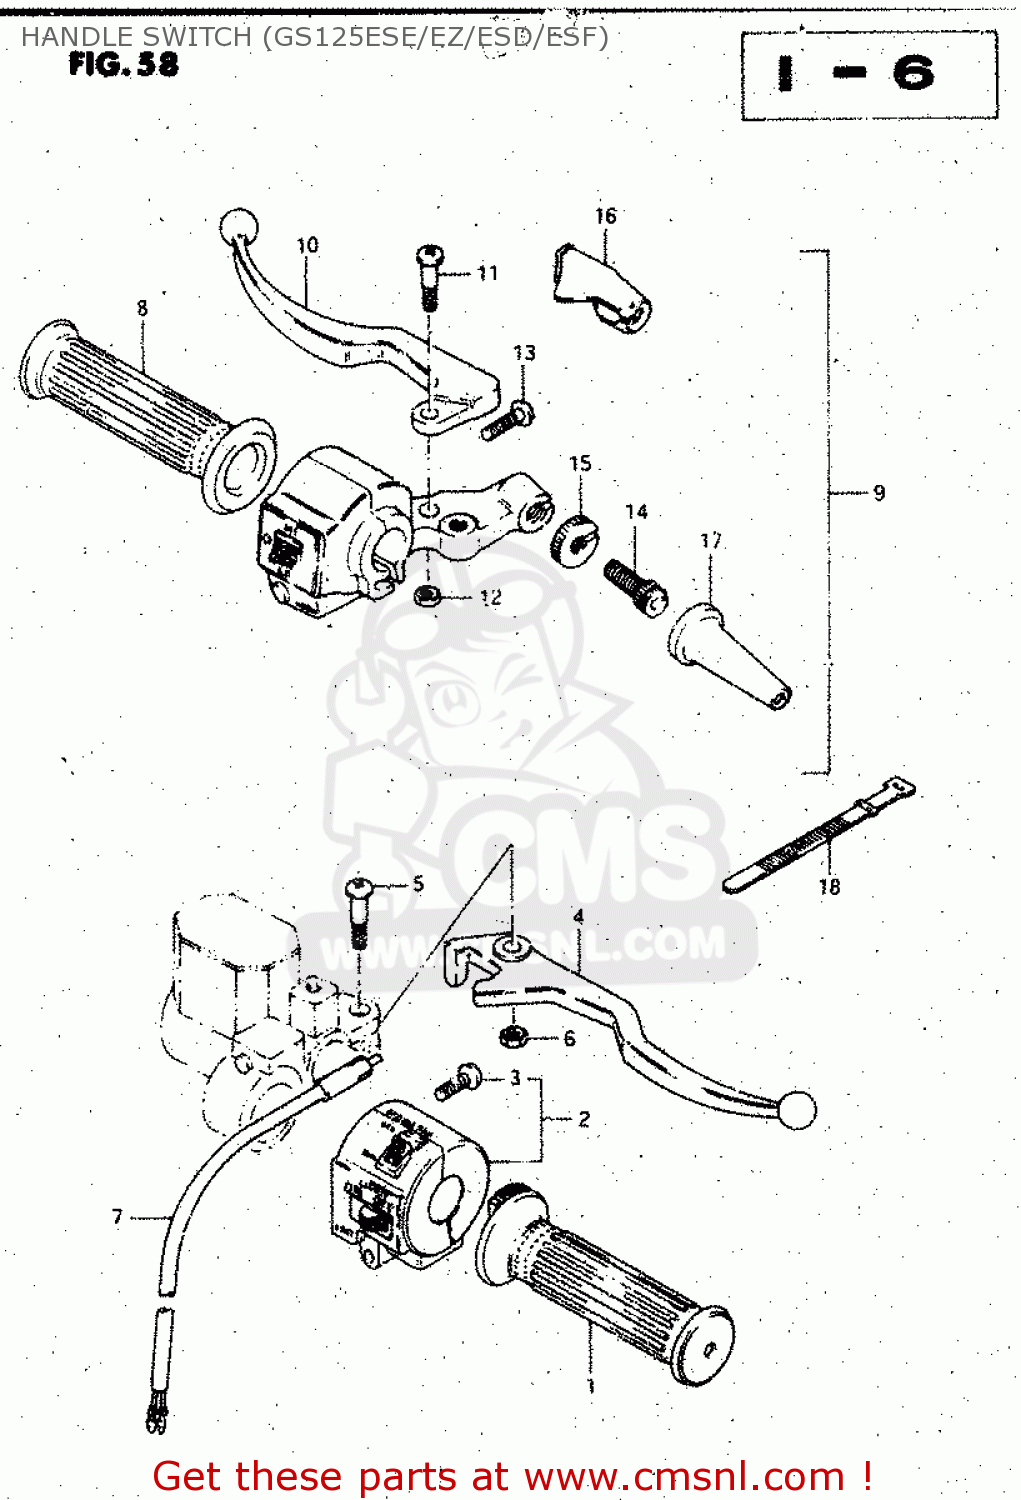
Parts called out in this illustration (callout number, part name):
1	GRIP, THROTTLE
2	SWITCH ASSY,HANDLE,R
3	SCREW 5X20
4	LEVER,BRAKE
5	SCREW
6	NUT
7	SWITCH ASSY,STOP
8	GRIP,L
9	LEVER ASSY,CLUTCH
10	LEVER,CLUTCH
11	SCREW
12	NUT 8MM
13	SCREW 5X20
14	ADJUSTER,CABLE
15	NUT,CABLE ADJUSTER
16	COVER,CLUTCH LEVER
17	BOOT,CLUTCH CABLE
18	CLAMP(L:120)
